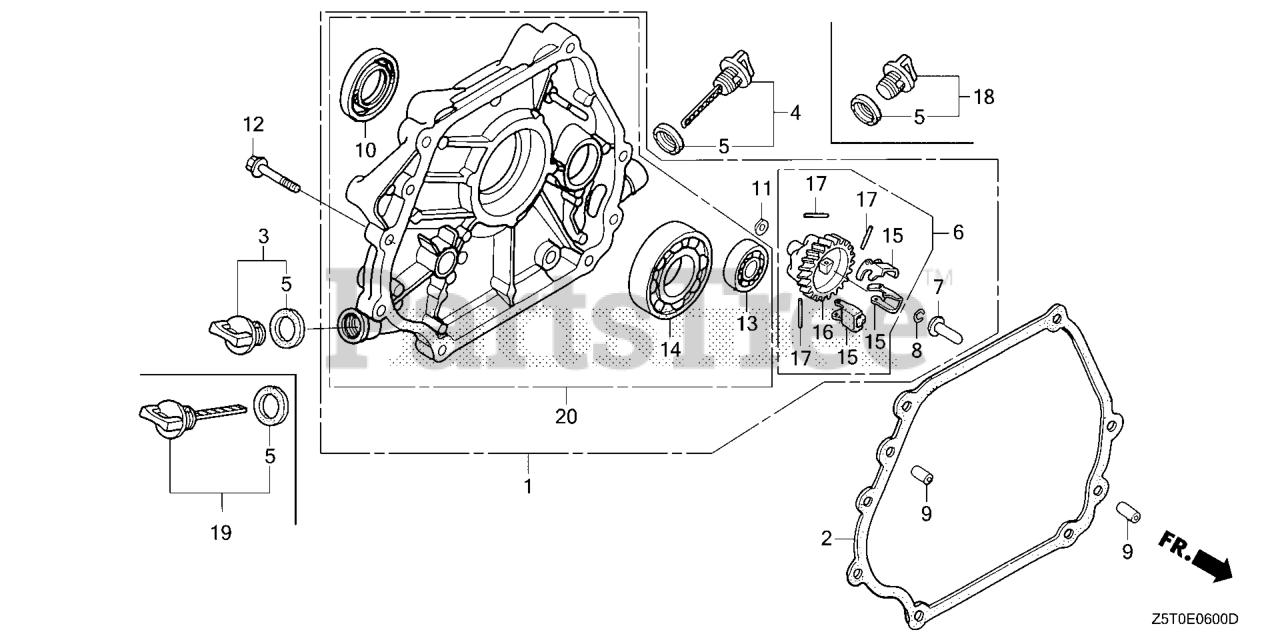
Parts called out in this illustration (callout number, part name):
1	COVER ASSY., CRANKCASE
2	GASKET, CRANKCASE COVER
3	CAP ASSY., OIL FILLER
4	CAP ASSY., OIL FILLER
5	GASKET, OIL FILLER CAP
6	GOVERNOR ASSY.
7	SLIDER, GOVERNOR
8	CLIP, GOVERNOR HOLDER
9	PIN, DOWEL (8X12)
10	OIL SEAL (35X52X8) (NOK)
11	WASHER, PLAIN (6MM)
12	BOLT, FLANGE (8X40) Use up to Engine SN 1003236.
13	BEARING, RADIAL BALL (6202) (FUJIKOSHI)
13	BEARING, RADIAL BALL (6202)
14	BEARING, RADIAL BALL (6207)
15	WEIGHT, GOVERNOR
16	HOLDER, GOVERNOR WEIGHT
17	PIN, GOVERNOR WEIGHT
